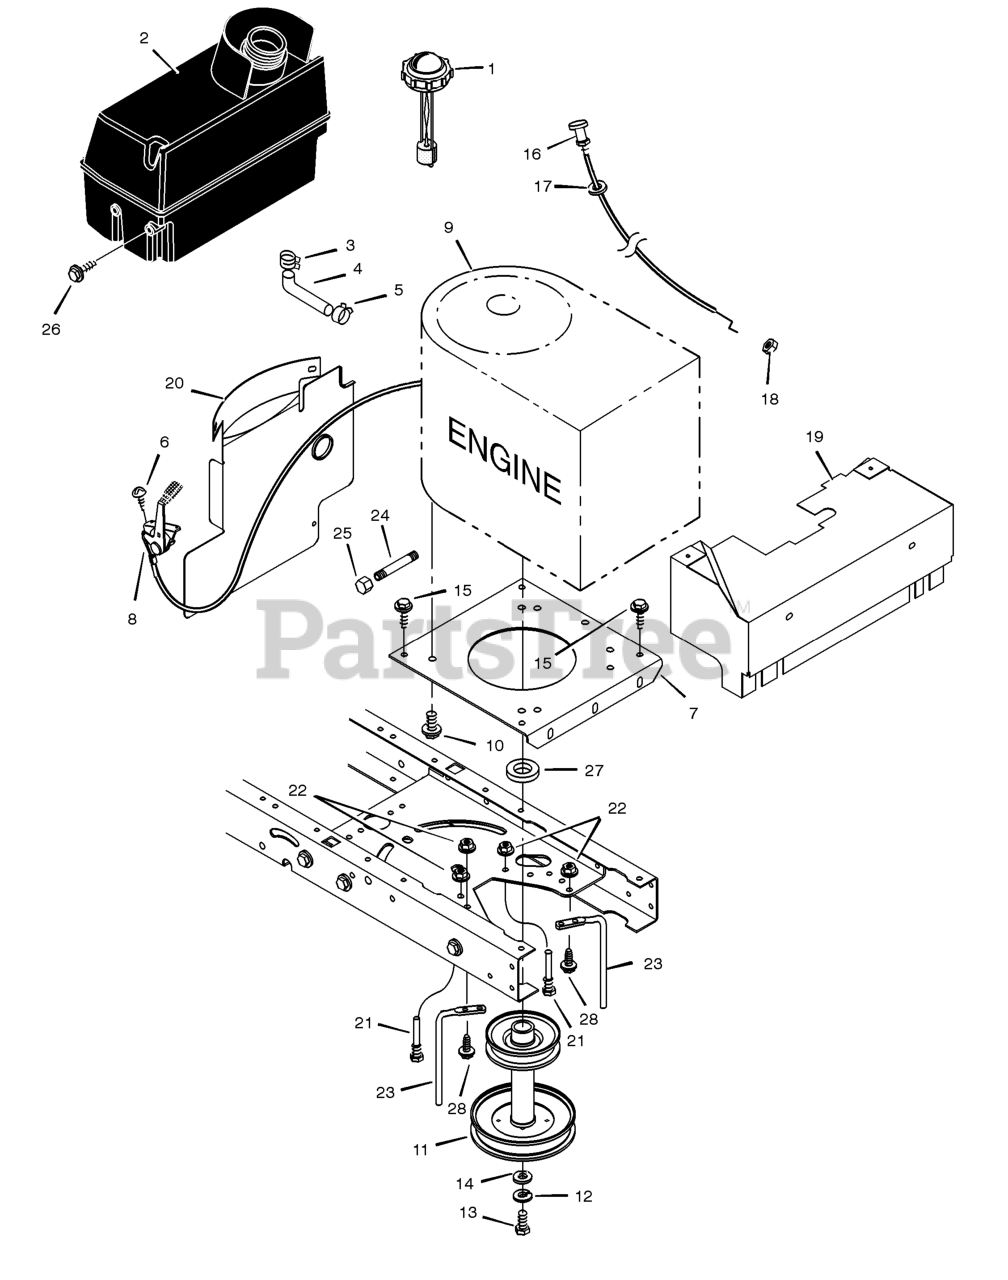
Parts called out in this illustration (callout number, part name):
1	Fuel Cap
2	Fuel Tank
3	Hose Clamp
4	Fuel Line (Must cut to length)
5	Hose Clamp
7	Plate, Engine
8	Throttle Control
9	Engine *
10	Bolt, Engine Mount
11	Stack Pulley Assembly
12	Lockwasher
13	Bolt, Hex
17	Washer
19	Shield, Heat
20	Baffle, Rear Engine
21	Guide, Belt
22	Nut, Flange
23	Guide, "L" Belt
24	Pipe, Oil Drain
25	Cap, Oil Drain
28	Screw
